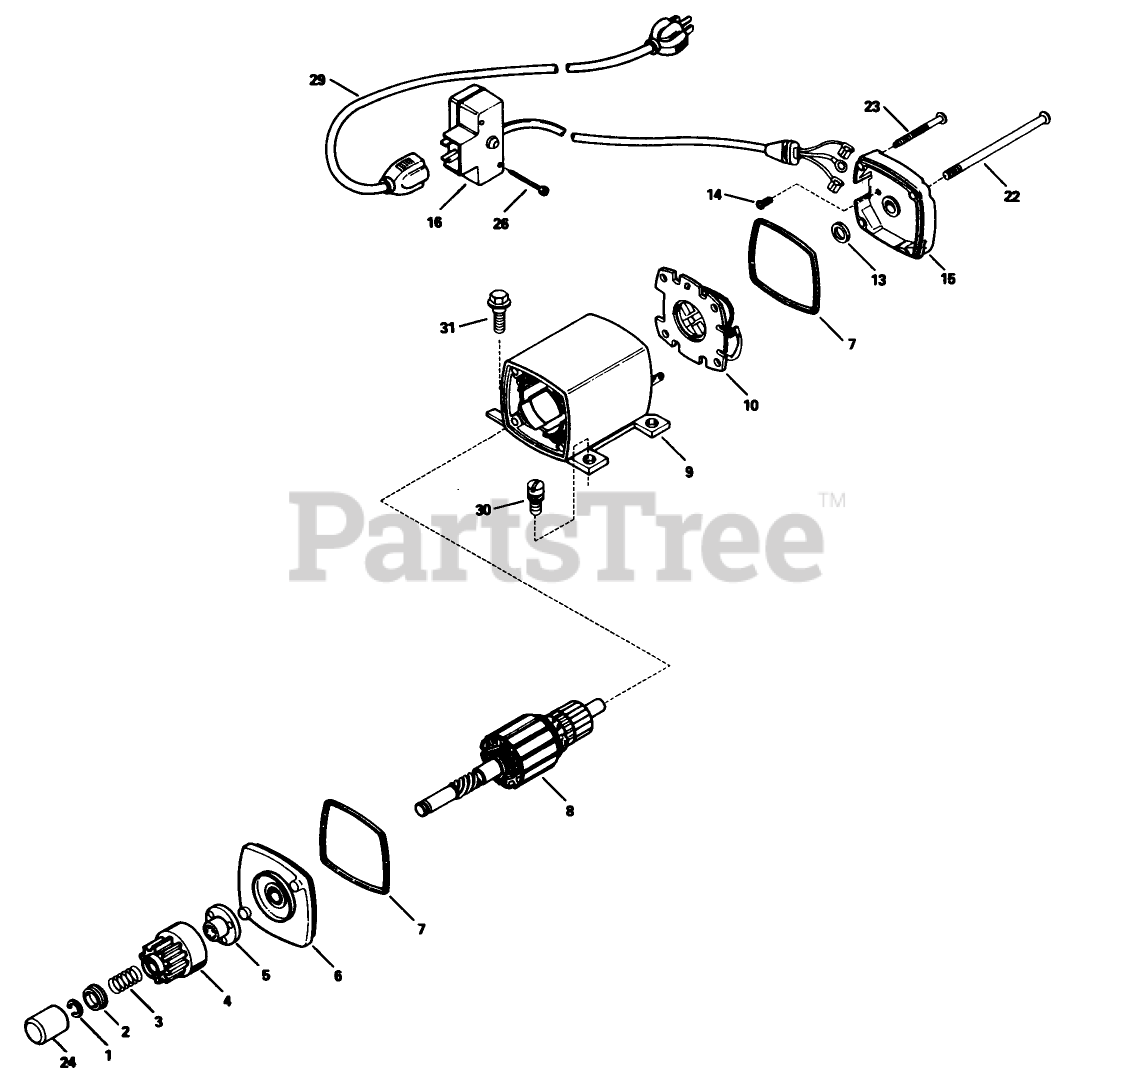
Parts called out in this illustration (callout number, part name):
1	Ring-Retainer
2	Retainer-Spring
3	Spring-Anti Drift
4	Gear
5	Nut-Engaging
6	Cap Assembly-Cap End (Incl. Ref. #7)
7	O-Ring
8	Armature
9	Housing Assy.
10	Card ASM
13	Washer-Thrust
14	Screw-Ground
15	Cap Assembly (Incl. Ref. #7)
16	Box Assembly-Switch (Incl. Ref. #26)
22	Bolt-Case
23	Screw-Ground
24	Cover-Dust
26	Screw
29	Cord-Extension
30	Screw
31	Screw (1/4-20x1/2)
